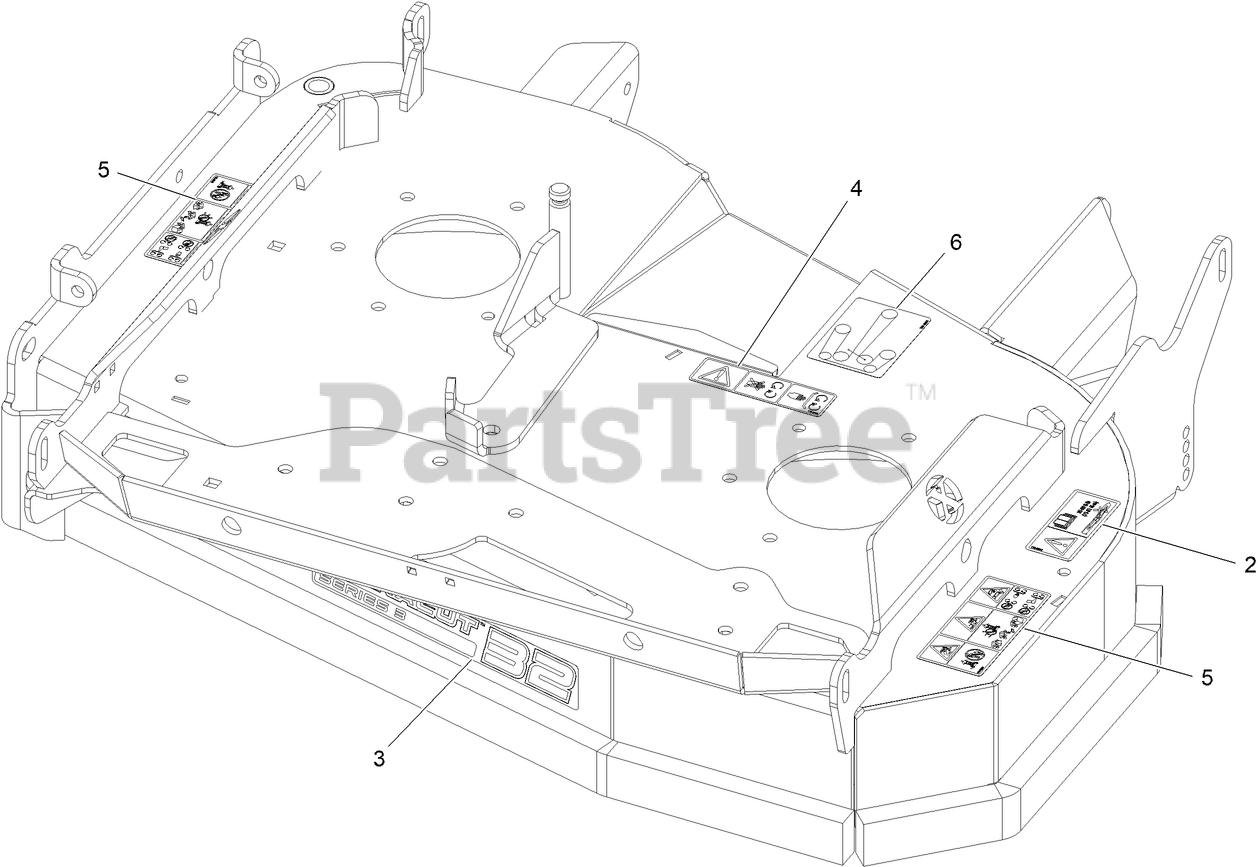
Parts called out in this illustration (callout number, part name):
2	DECAL-TORQUE, BOLT
3	DECAL-ULTRACUT 32-SERIES 3
4	DECAL-COVER, MISSING
5	DECAL-WARNING THROWN OBJECT
6	DECAL-BELT ROUTING
